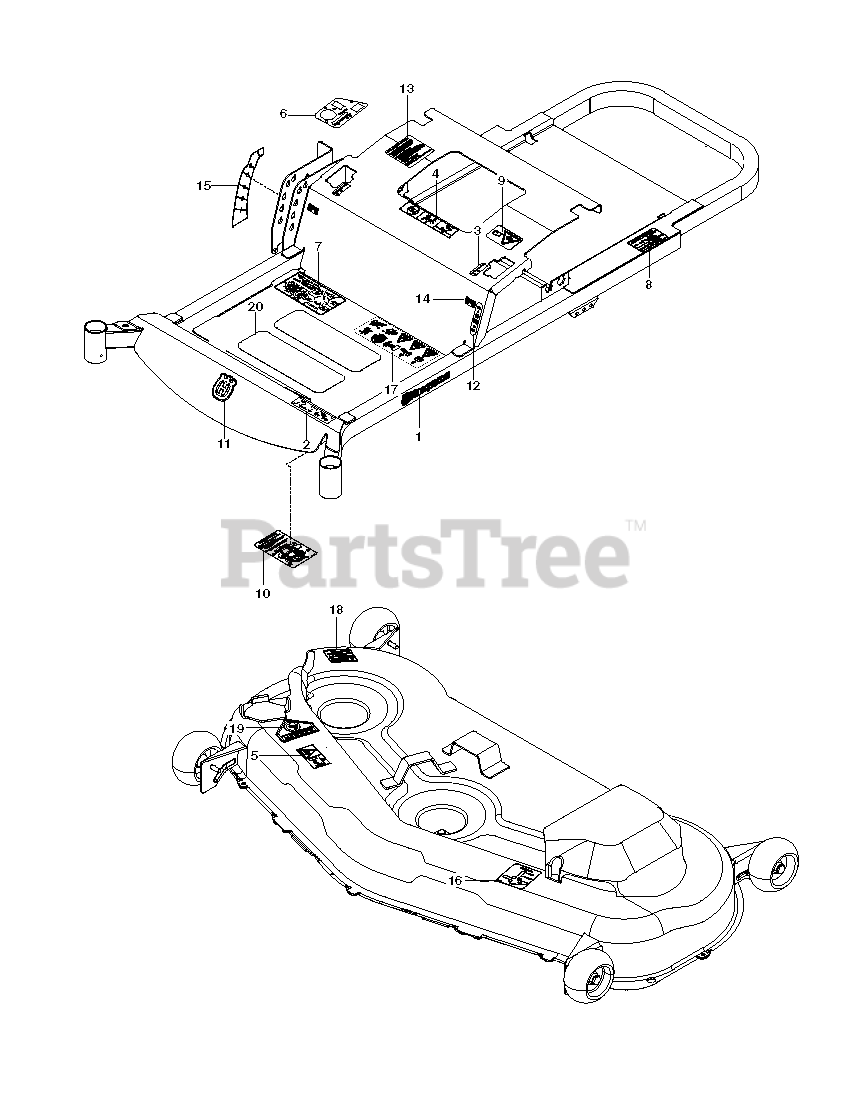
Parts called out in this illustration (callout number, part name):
1	RP.DECAL.BADGE.170MM.TEXTLOGO
2	DECAL.RZ54I
3	DECAL, MOTION CONTROL
4	EURO DECAL-BATTERY WARNIN6
5	DECAL, EURO SEVERING
6	DECAL.ZTR.CONTROL.PANEL
7	DECAL.ZTR.STARTING.SMARTLIGHT
8	DECAL, DO NOT TOW
9	DECAL, EXITING MOWER
10	DECAL, SERVICE
11	DECAL.AUGER.HUSQ.CROWN.SNOW
12	DECAL, PARK BRAKE
13	DECAL, CUSTOMER RESPNSIBILITY
14	DECAL, F.S.T.
15	DECAL, DECK HEIGHT, HUSQ
16	DECAL, BELT ROUTING
17	DECAL.ZTR.WARNING.SMARTIGNITIN
18	DECAL.DECK.6MIL./DEF.SHLD.WARN
19	DECAL, CPSC
20	ANTI-SKID PAD
